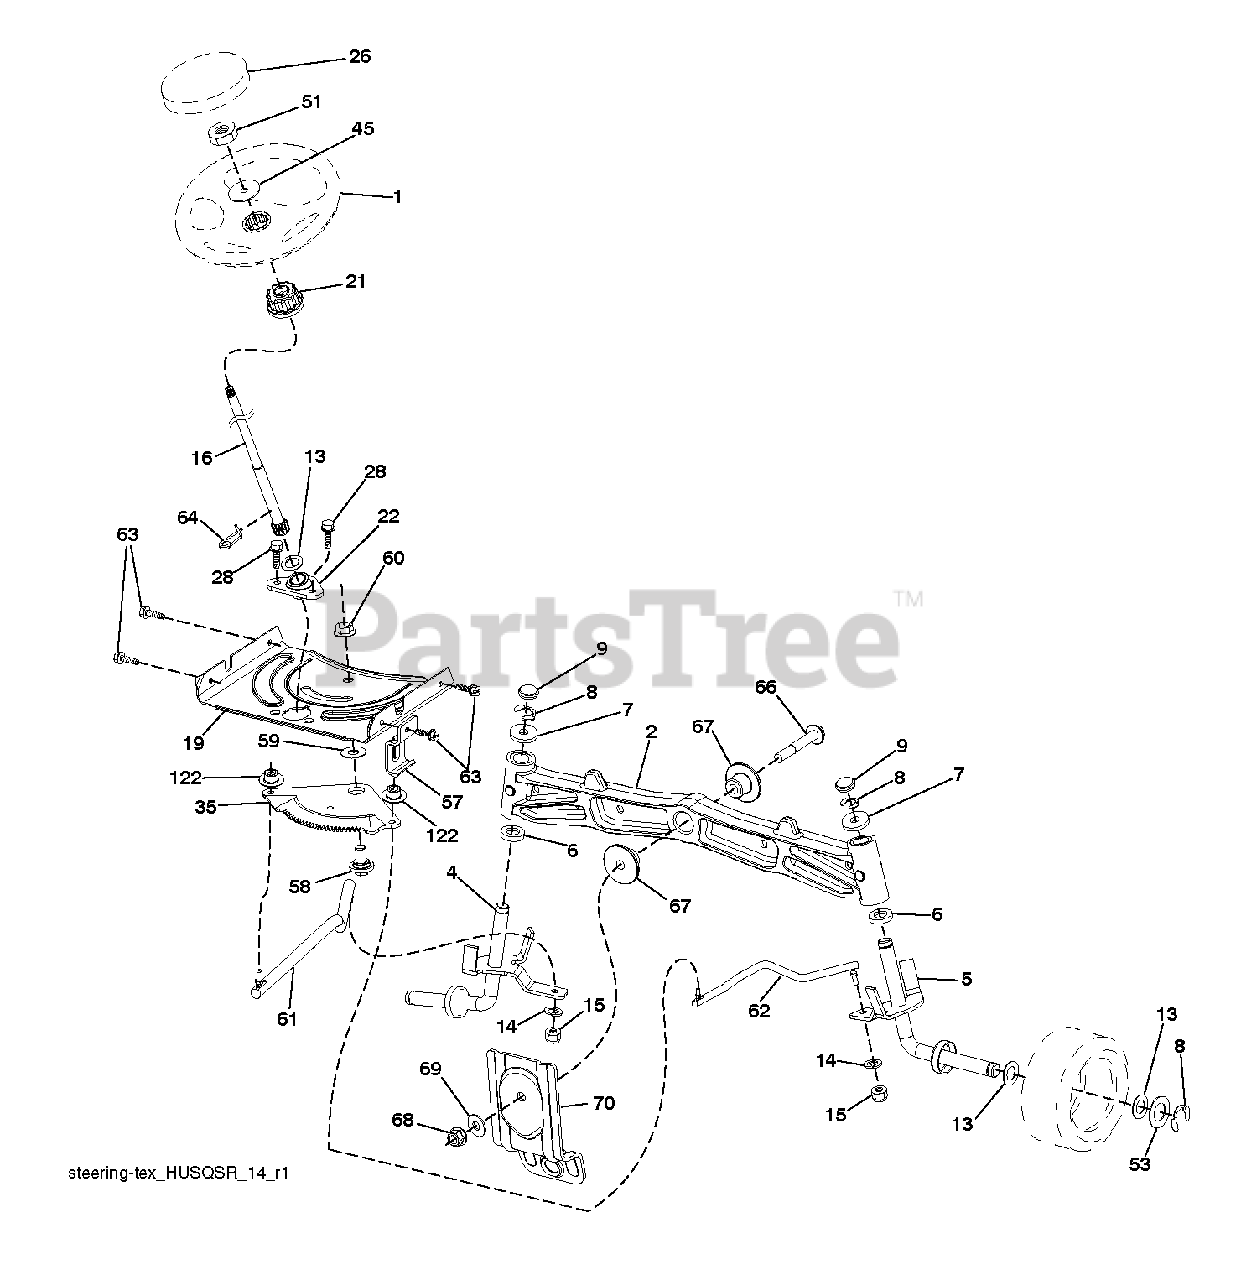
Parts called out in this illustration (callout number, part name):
1	WHEEL.STEER.HUSQ.SR.498.OVMLD
2	AXLE.CAST.IRON
4	SPINDLE.WELDED.LH.15"TEX
5	SPINDLE.WELDED.RH.15"T
6	THRUST WASHER
9	CAP.SPINDLE.BLACK
14	WASHER, LOCK 3/8
15	NUT CROWNLOCK 3/8-24
16	SHAFT, STEERING
19	PLATE.STEER.DDL.NLT/NG
21	ADAPTER, WHEEL STNG..
22	STEERING.SUPT.LOWER.
26	INSERT.CAP.WHL.STRG.HUSQ.PREM
28	SCREW, 3/8-16X3/4
35	GEAR.SECTOR.PLATE.DDL.
45	WASHER 9/16"ID, 2 3/8"OD
51	NUT.HEX.1/2-20
53	WASHER.HARDENED
57	BRKT.UPSTOP.GT/LT.TEX
58	BOLT.SHOULDER.SECTOR.P
59	WASHER.THURST.SECTOR.S
60	NUT FLANGE LOCK 5/8-11
61	DRAGLINK.LH.BALLSTUD.D
62	DRAGLINK.RH.BALLSTUD.D
63	SCREW
64	RETAINER.CLIP.SPRING.S
66	BOLT HEX FGHD 7/16-14 X 3 SERR
67	BUSHING.PM.FRONT AXLE
68	NUT.LOCK.FLANGE.7/16
69	WASHER.1.5X.505X.118
70	BRKT.DECK.SUSPENSION.F
122	CAP.GEAR.SECTOR.TEX
